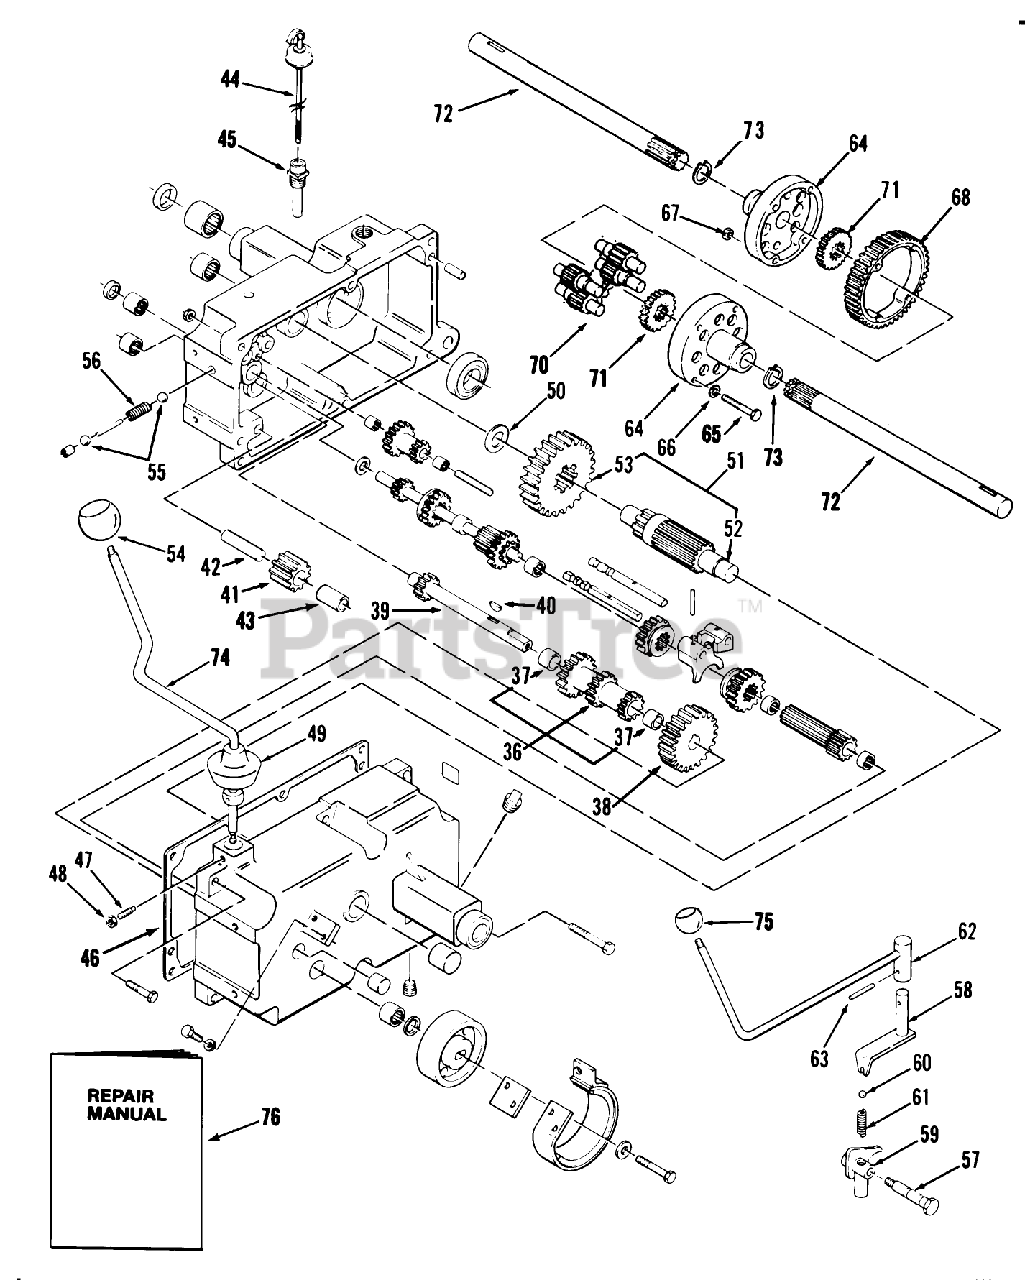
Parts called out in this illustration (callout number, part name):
36	GEAR-CLUSTER
37	BUSHING-BRONZE
38	GEAR-CLUSTER SHAFT
40	KEY-WOODRUFF
41	GEAR/BUSHING ASM-REVERSE IDLER
42	PIN-DIFFERENTIAL
43	BUSHING
45	NIPPLE-TRANS FILL
46	GASKET-TRANSMISSION
47	SETSCREW
49	COVER-DUST
50	WASHER-THRUST
51	GEAR ASM
52	PINION SHAFT
55	BALL-DETENT
56	SPRING-SHIFT STOP
57	BOLT-DETENT
58	SHIFT ASM
60	BALL-DETENT
61	SPRING-SHIFT STOP
62	SHIFT ROD ASM
63	PIN-SPIROL
66	WASHER
67	NUT-HEX
70	GEAR-PINION, 11T
71	AXLE GEAR
76	MANUAL
